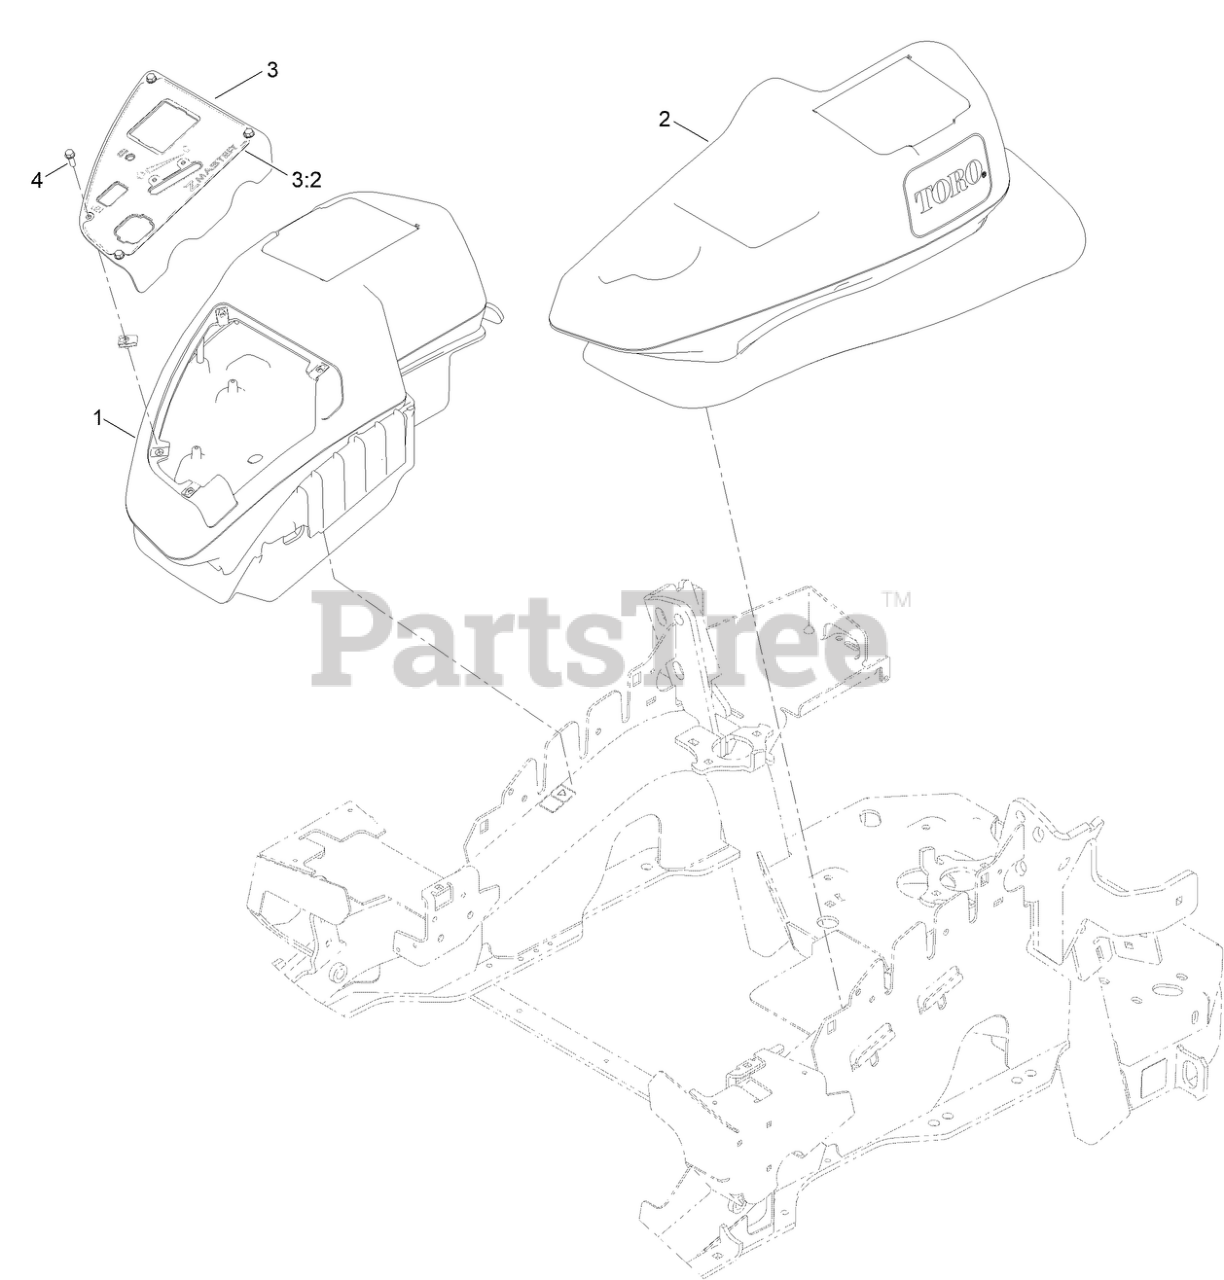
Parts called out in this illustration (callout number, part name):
1	RH CONSOLE ASM
2	LH CONSOLE ASM
3	CONTROL PANEL W/ DECAL ASM
3:2	DECAL-CONTROL PANEL
4	SCREW-HWH
